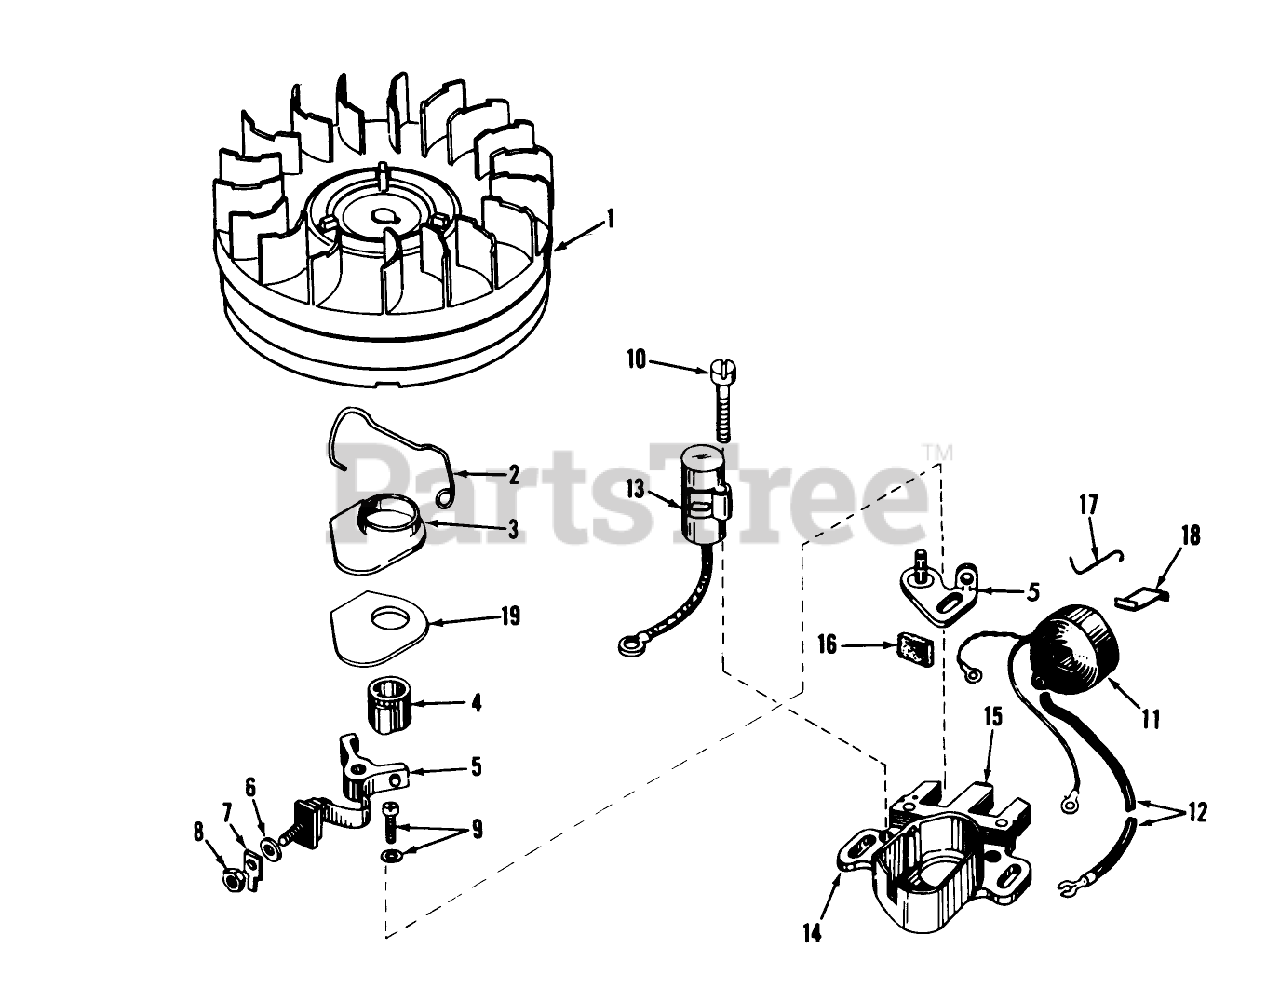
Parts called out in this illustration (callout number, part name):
1	Flywheel
2	Spring Breaker Box
3	Cover, Dust
4	Cam, Breaker
5	Breaker Assy.
6	Washer
7	Terminal, Ground
8	DECAL
9	Breaker Screw
10	Condenser Screw
11	Coil Assy. (Incl. No. 12)
12	Wire, Lead
13	Condenser
14	Core Plate
15	Stator Assy., (Incl. Nos. 2, 3, 5 thru 14 16 thru 19)
16	Felt,Cam Wiper
17	Clip, Coil
18	Spring Coil Wedge
19	Gasket Dust Cover
